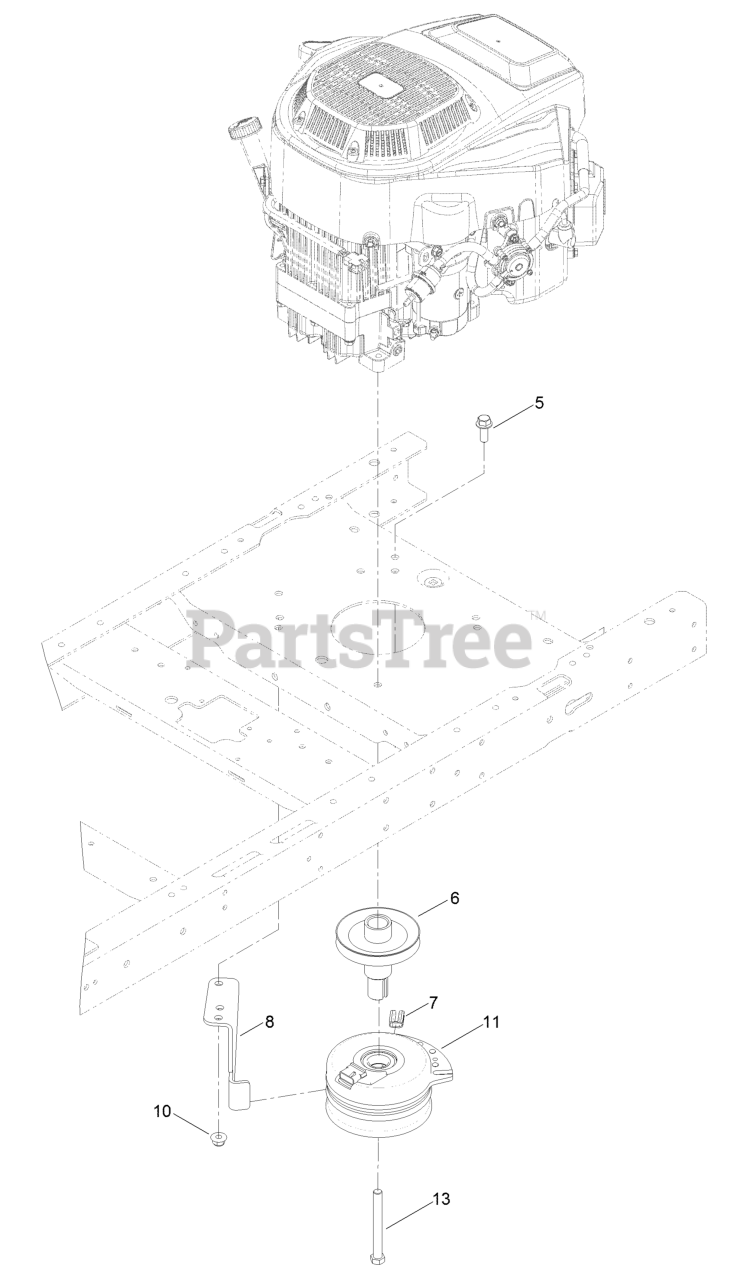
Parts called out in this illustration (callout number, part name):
5	SCREW-HHF 3/8-16 X 1
6	PULLEY-ENGINE
7	ISOLATOR-CLUTCH
8	STOP-CLUTCH (NARROW)
10	NUT-HF, NI
11	CLUTCH-ELECTRIC
13	PIN-ROLL, SLOTTED
